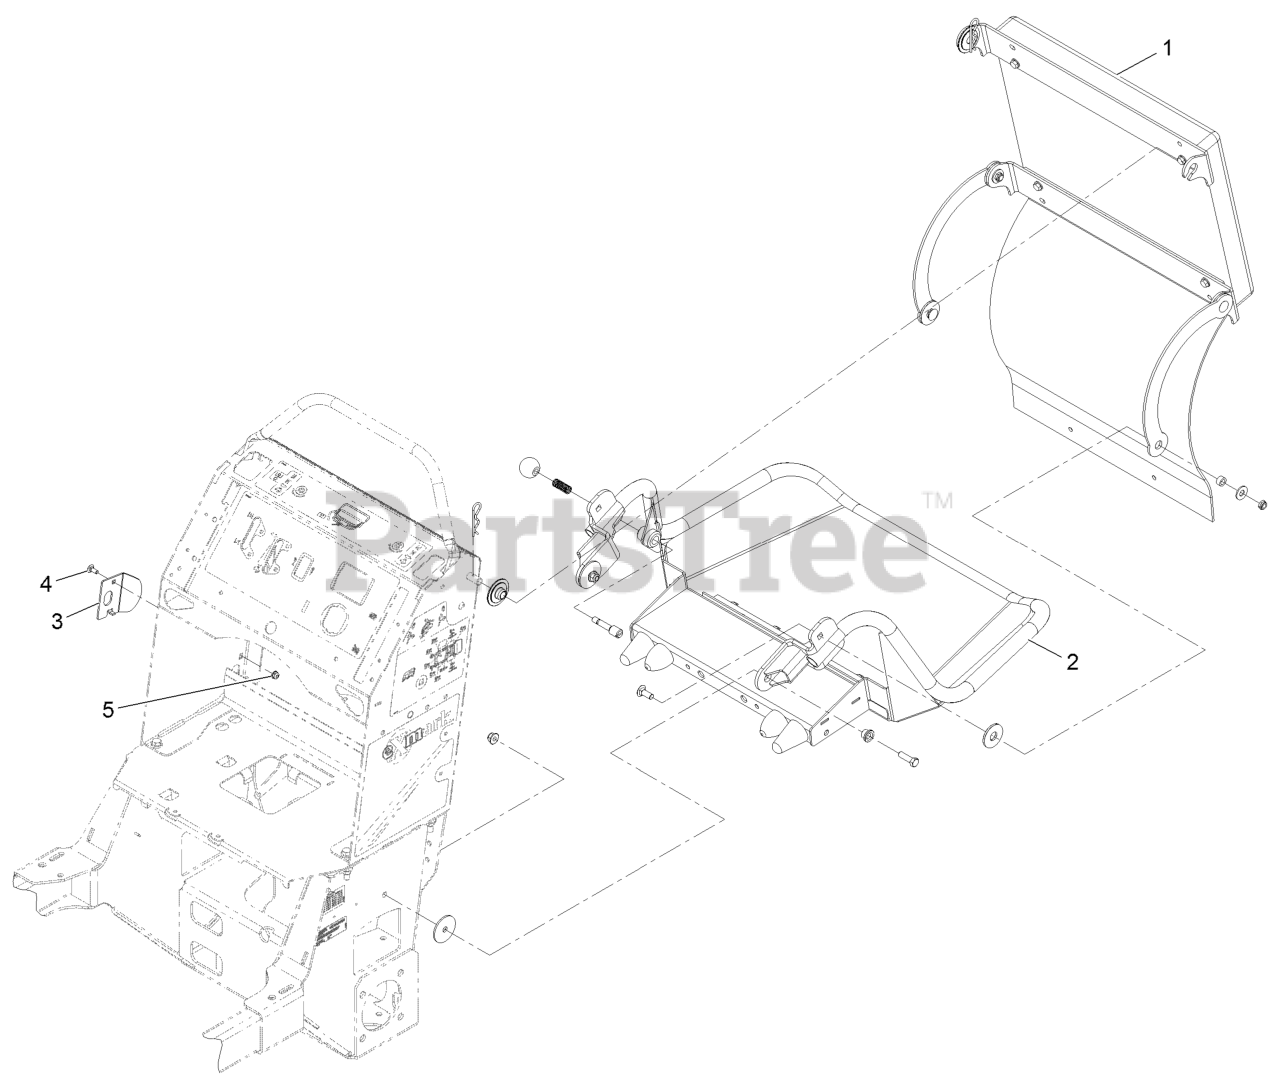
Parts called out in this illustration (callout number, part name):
1	ASM, CUSHION
2	PLATFORM ASM
3	PLATE-STRIKER
4	SCREW-CARR
